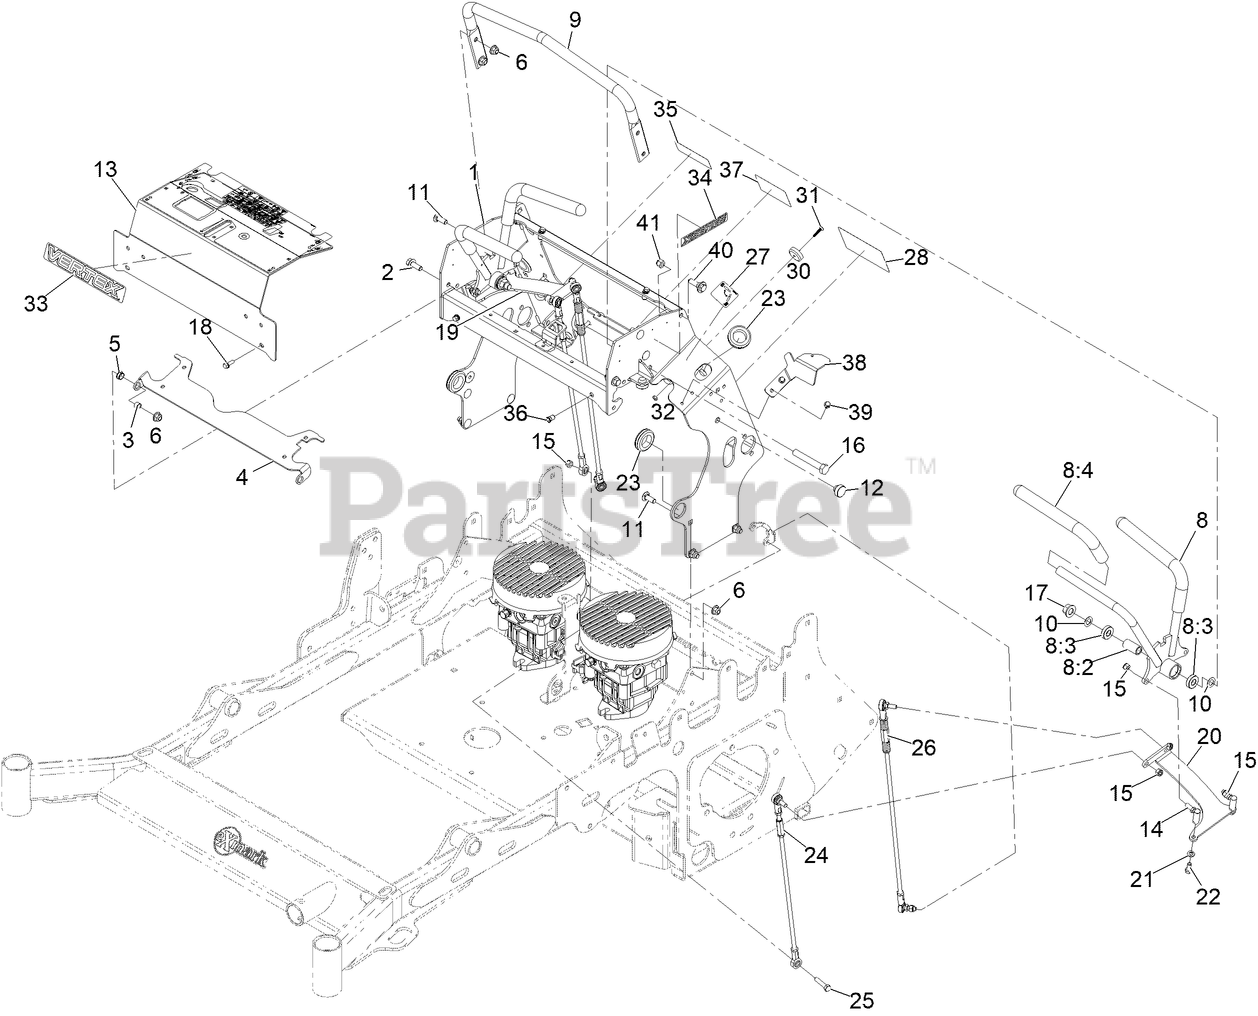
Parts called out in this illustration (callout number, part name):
1	ASM-Tower Weld [red]
2	SCREW-HHF 3/8-16 X 1
3	SPACER-BRAKE PIVOT
4	PLATE-MOTION CNTRL LOCK
5	BUSHING,SNAP
6	NUT-HF, NI
8	ASM-Ctrl Lever
8:3	BEARING-BALL
8:4	GRIP-HANDLE, CONTROL
9	BAR-REFERENCE
11	SCREW-CARR
12	BUMPER-RUBBER
13	ASM-Ctrl Pnl W/Dcl Non-EFI
14	BALLJOINT-RH (W/GROMMET)
15	NUT-LOCK
16	SCREW-HH
17	Nut-Lock 1/2-13
18	SCREW-HHF
19	BRACKET-LINK CTRL LH
20	BRACKET-LINK CTRL RH
21	WASHER-LOCK
22	SCREW-HH
23	GROMMET
24	ASM-MOTION CONTROL SHORT
25	SCREW-HH
26	ASM-MOTION CONTROL LONG
27	DECAL-PARK BRAKE, CE
28	DECAL-SERVICE AID
30	MAGNET-RARE EARTH THIGH PAD
31	SCREW FLAT HD #10-24X1.00
32	NUT-LOCK
33	DECAL-VERTEX LOGO
34	DECAL-X-SERIES
35	DECAL-FUSE
36	Nut-Clinch, Hex
37	DECAL-DRIVE RELEASE
38	BRACKET-FUEL LINE CLAMP LH
39	SCREW-HWH
40	SCREW-SHOULDER, HWH
41	NUT-LOCK, NI
